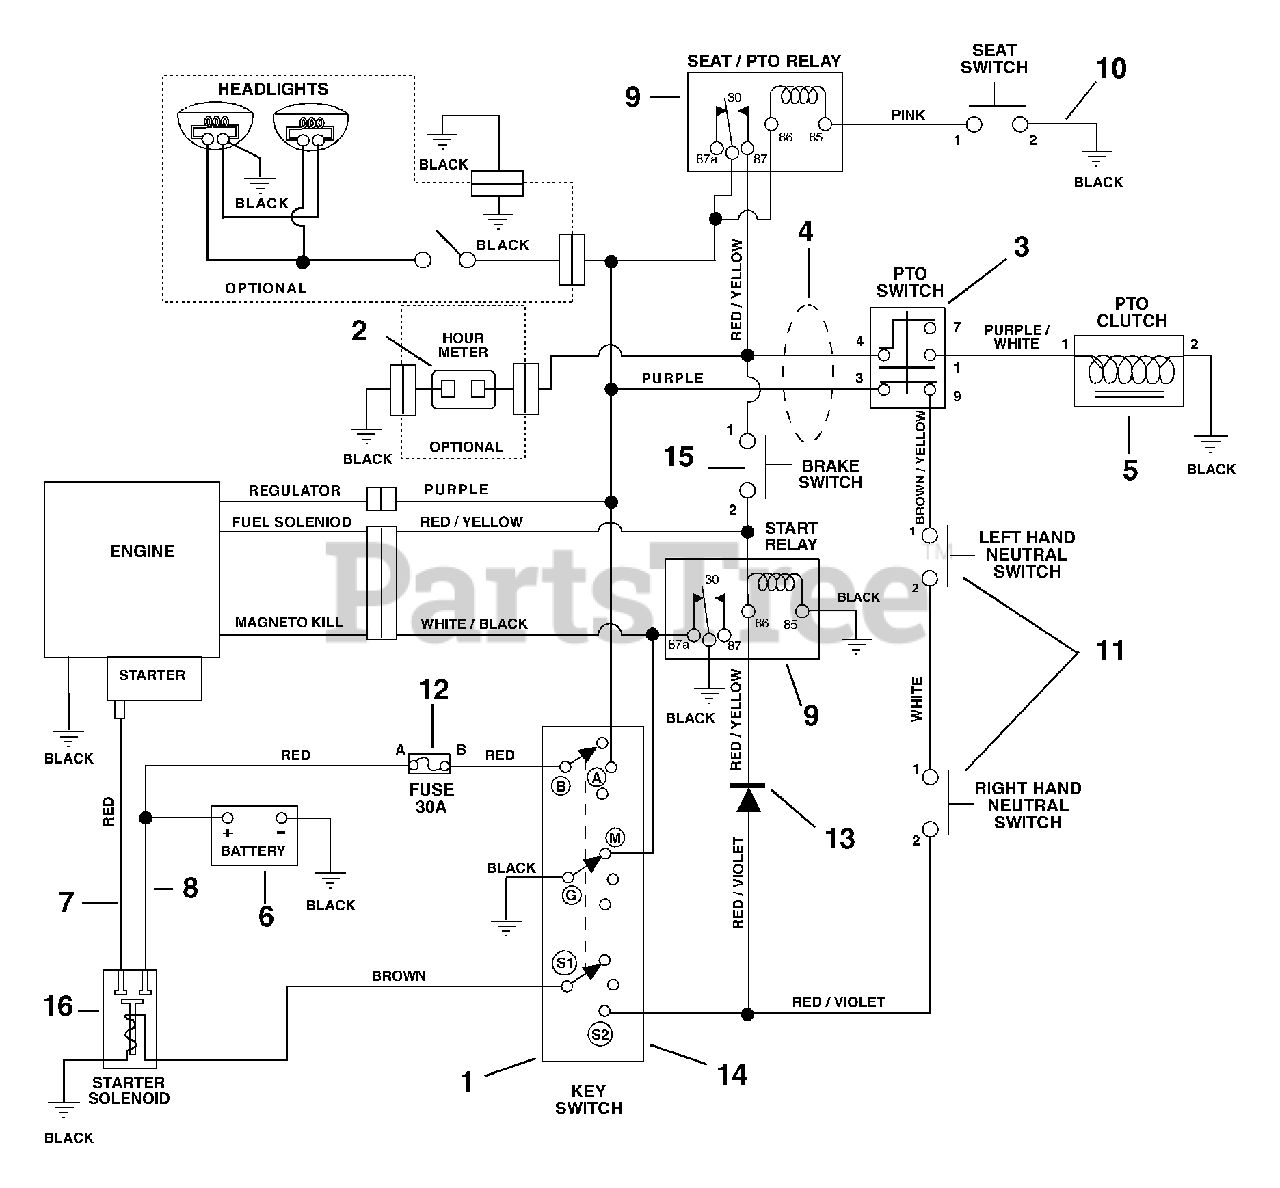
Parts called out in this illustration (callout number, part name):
1	Key Switch
2	Hour Meter
3	Switch-Clutch
4	Harness-Wire
5	Clutch / Brake-Electric
7	Start Cable
8	Starter Cable
9	Relay
10	Switch-Seat
11	Switch-Neutral
12	30 AMP Fuse
13	Plug-Molded Diode
14	Cap-Ignition Switch
15	Switch-Brake
16	Solenoid
